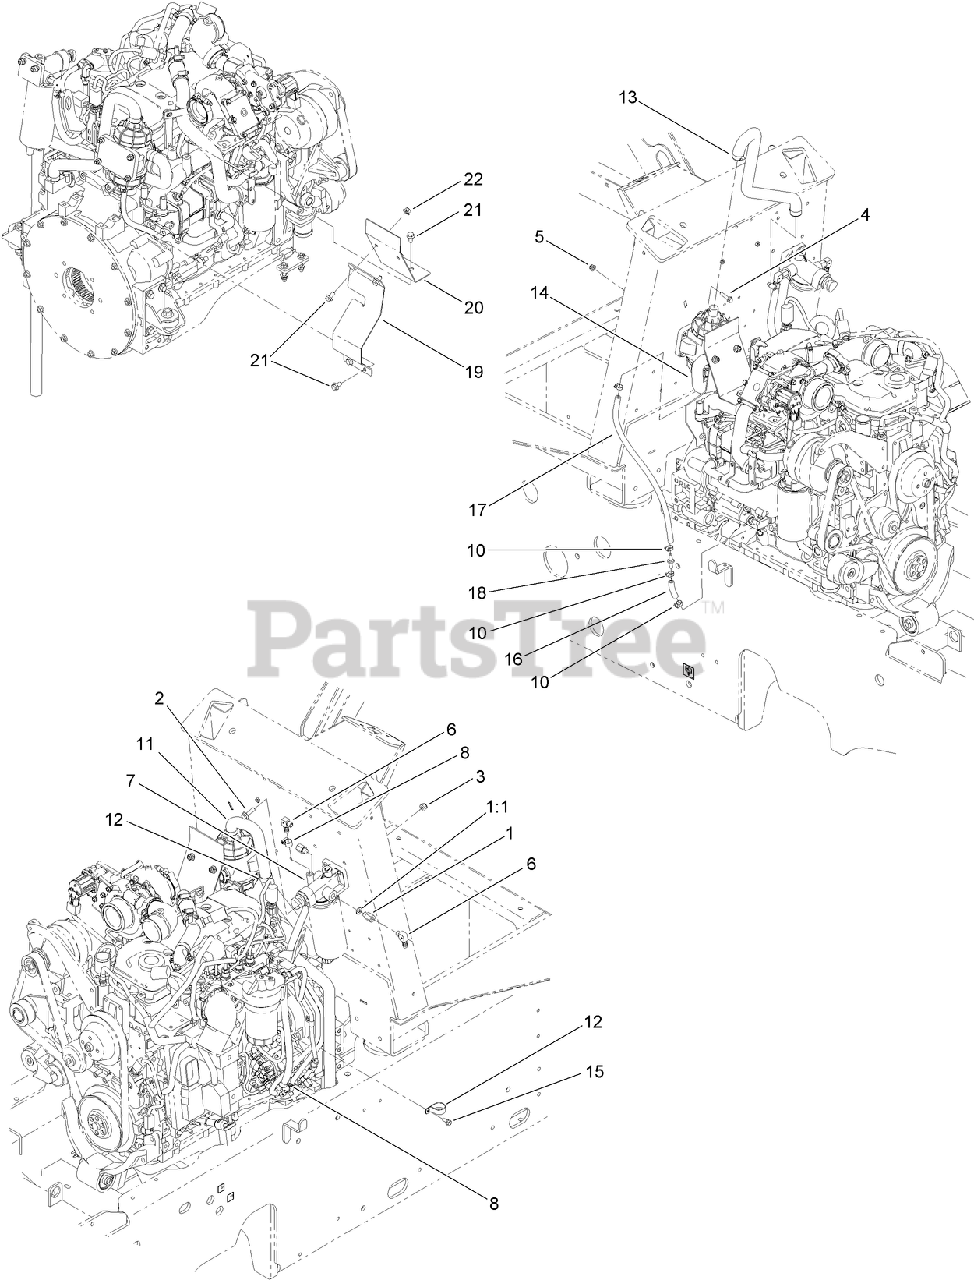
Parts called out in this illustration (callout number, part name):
1	FITTING-REDUCER
1:1	SEAL-FITTING, FUEL
2	SCREW-HHF
3	NUT-LOCK, NI
4	SCREW-HHF
5	NUT-LOCK, HHF
6	FITTING-ELBOW, 90
7	HOSE-FUEL
8	CLAMP-HOSE, WORM DRIVE
10	CLAMP-WORM
12	R-CLAMP
13	CLAMP-HOSE
15	SCREW-HHF
16	HOSE-BREATHER
17	HOSE-BREATHER
18	VALVE-CHECK
19	PLATE-HEAT SHIELD, LOWER
20	PLATE-HEAT SHIELD, UPPER
21	SCREW-HHF
22	NUT-HF
